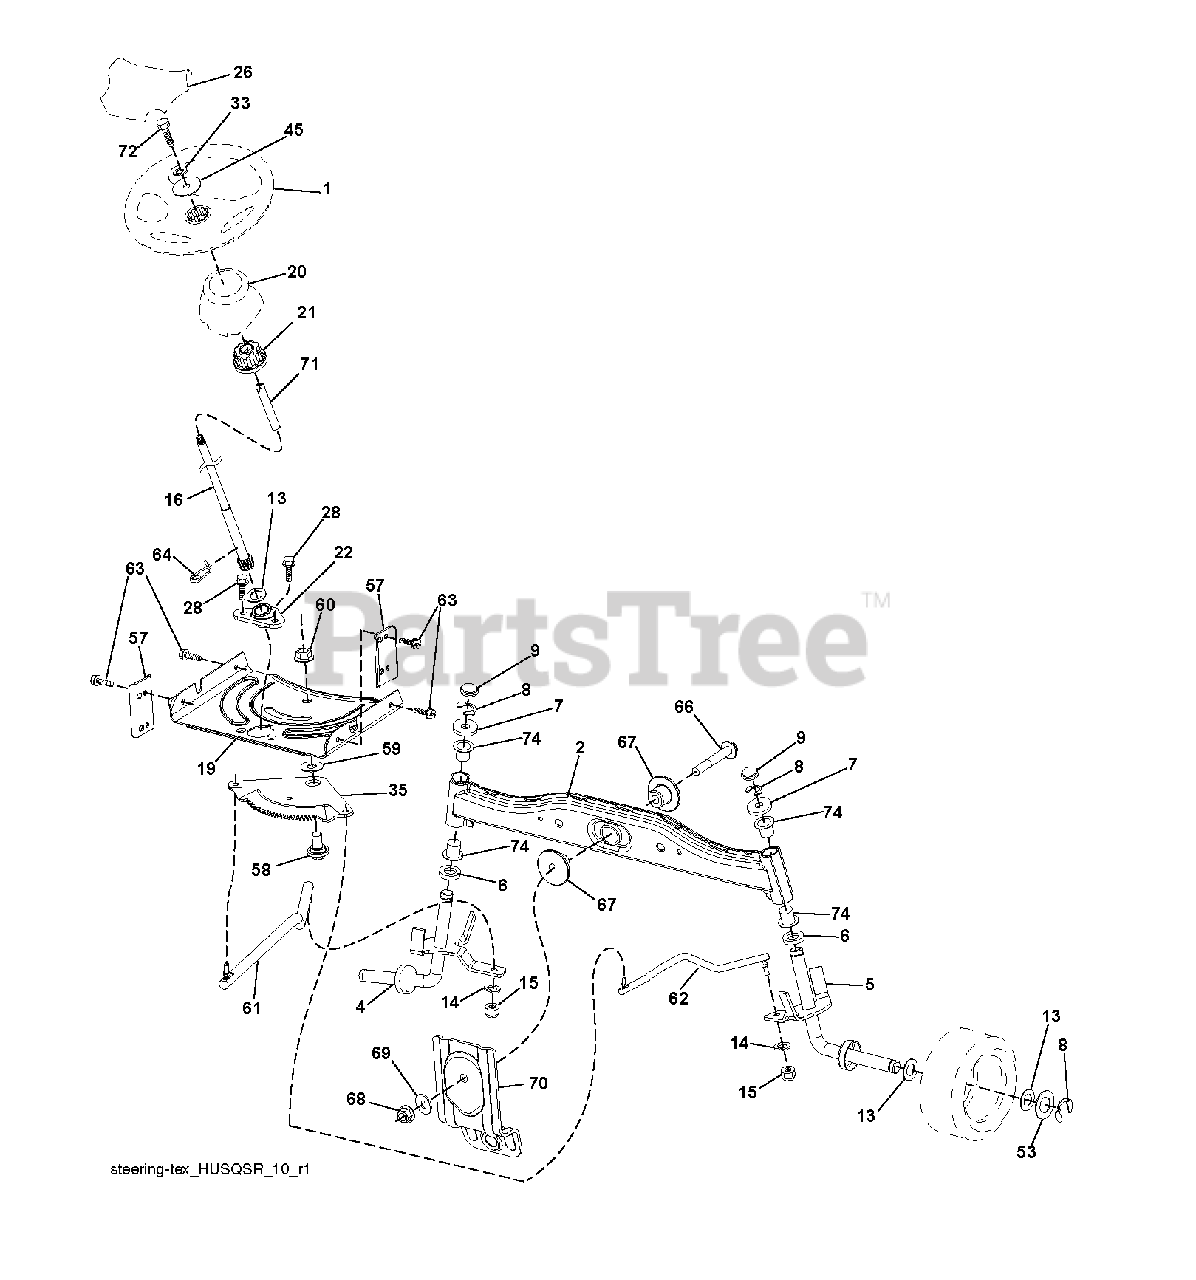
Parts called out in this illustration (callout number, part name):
1	WHEEL.STEERING.PREM.2.BLK
2	AXLE HALF ASM-WELDED
4	SPINDLE.WELDED.LH.15"TEX
5	SPINDLE.WELDED.RH.15"T
8	RING CLIP
9	CAP.SPINDLE
14	WASHER, LOCK 3/8
15	NUT CROWNLOCK 3/8-24
16	SHAFT.STEER.3/4.PLATED.TEX
19	PLATE.STEER.DDL.NLT/NG
20	BOOT STEERING BLACK
21	ADAPTER, WHEEL STNG..
22	STEERING.SUPT.LOWER.
26	INSERT.CAP.STRG.WH.BLACK
28	SCREW, 3/8-16X3/4
33	LOCKWASHER
35	GEAR.SECTOR.PLATE.DDL.
45	WASHER.11/32
53	WASHER.HARDENED
57	BRACKET.UPSTOP.TEX
58	BOLT.SHOULDER.SECTOR.P
59	WASHER.THURST.SECTOR.S
60	NUT FLANGE LOCK 5/8-11
61	DRAGLINK.LH.BALLSTUD.D
62	DRAGLINK.RH.BALLSTUD.D
63	SCREW
64	RETAINER.CLIP.SPRING.S
66	BOLT HEX FGHD 7/16-14 X 3 SERR
67	BUSHING.PM.FRONT AXLE
68	NUT.LOCK.FLANGE.7/16
69	WASHER.1.5X.505X.118
70	BRKT.DECK.SUSPENSION.F
71	SHAFT.EXTEN.STRG.SPLINE
72	BOLT 5/16-18 X 4 W/PATCH
74	BRNG T
